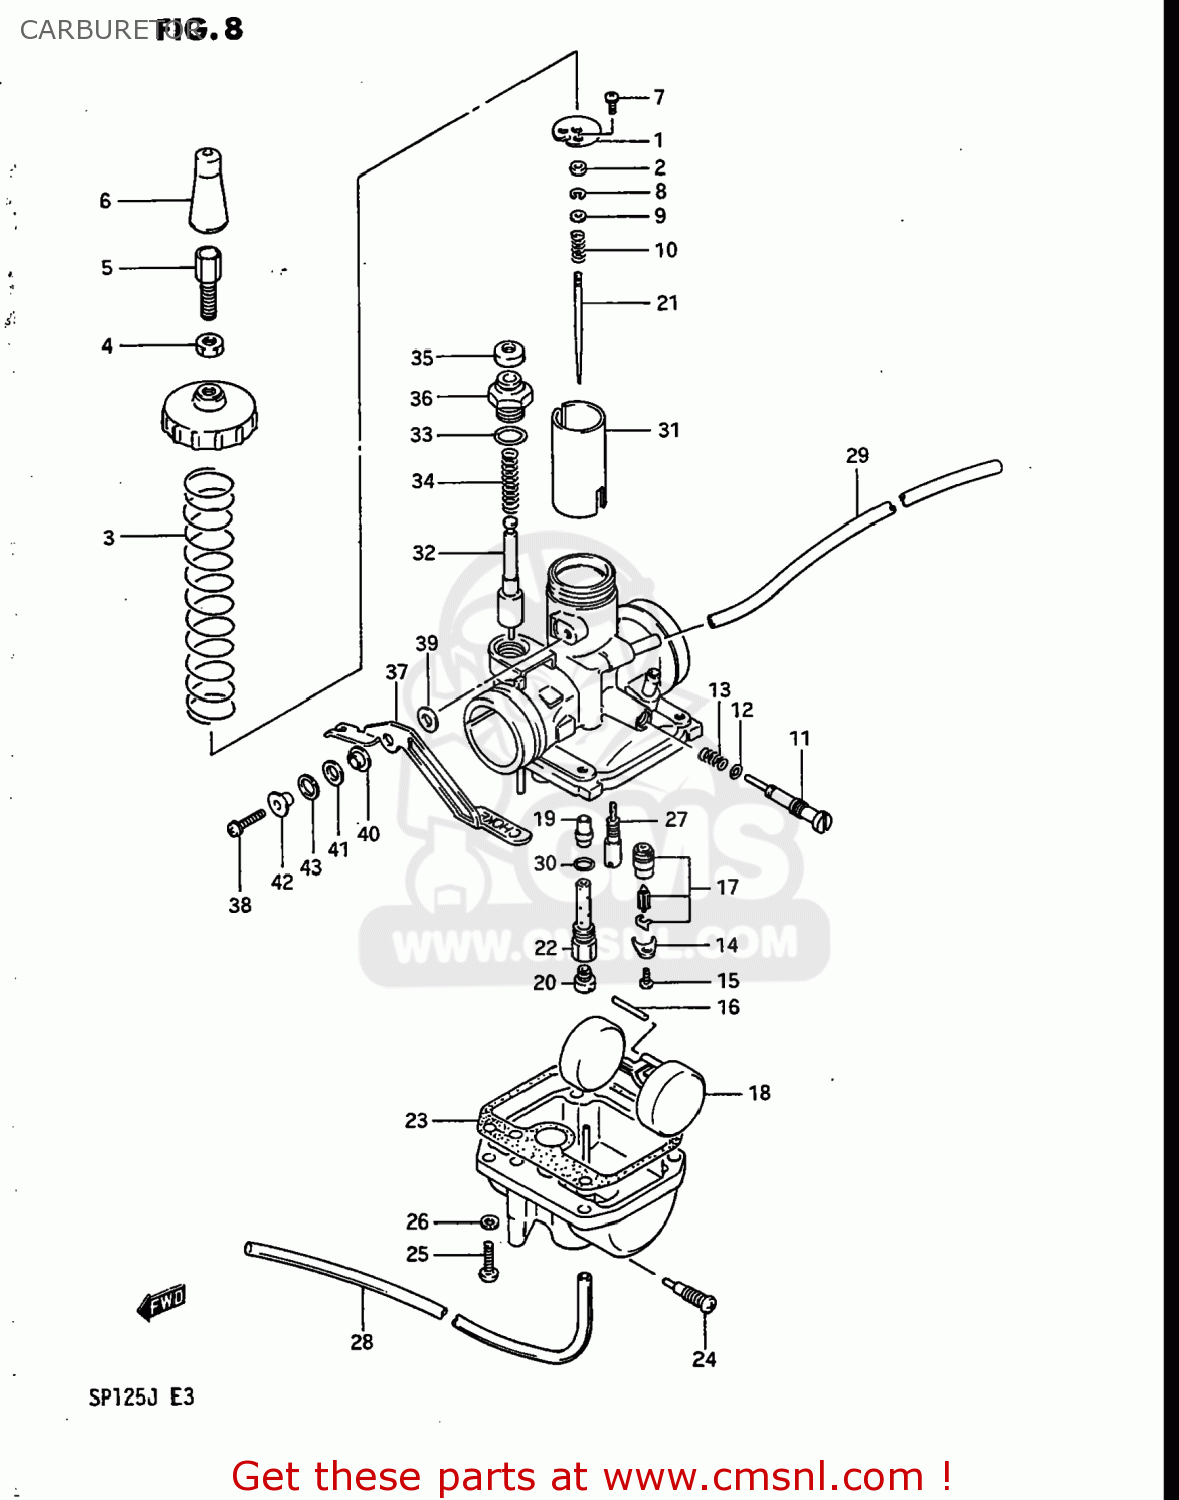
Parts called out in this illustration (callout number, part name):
1	PLATE,NEEDLE VALVE FITTING
2	RING
3	SPRING,THROTTLE VALVE
4	NUT
5	ADJUSTER,CABLE
6	CAP,RUBBER
7	SCREW
8	CLIP
9	WASHER,JET NEEDLE
10	SPRING
11	SCREW,THROTTLE STOP
12	O RING
13	SPRING
14	PLATE,NEEDLE VALVE FITING
15	SCREW
16	PIN,FLOAT
17	VALVE ASSEMBLY,NEEDLE
18	FLOAT
19	JET,NEEDLE(N-9)
20	JET,MAIN(95)
21	NEEDLE JET
22	PIPE
23	GASKET,FLOAT CHAMBER
24	PLUG,DRAIN
25	SCREW
26	WASHER,LOCK 4M
27	JET,PILOT(22.5)
28	HOSE
29	HOSE
30	O RING
31	(CA) VALVE,THROTTLE
32	PLUNGER ASSY
33	O RING
34	SPRING
35	CAP,STARTER VALVE
36	HOLDER
37	LEVER
38	SCREW
39	PLATE
40	RING
41	WASHER
42	RING
43	WASHER,LOCK,8.
